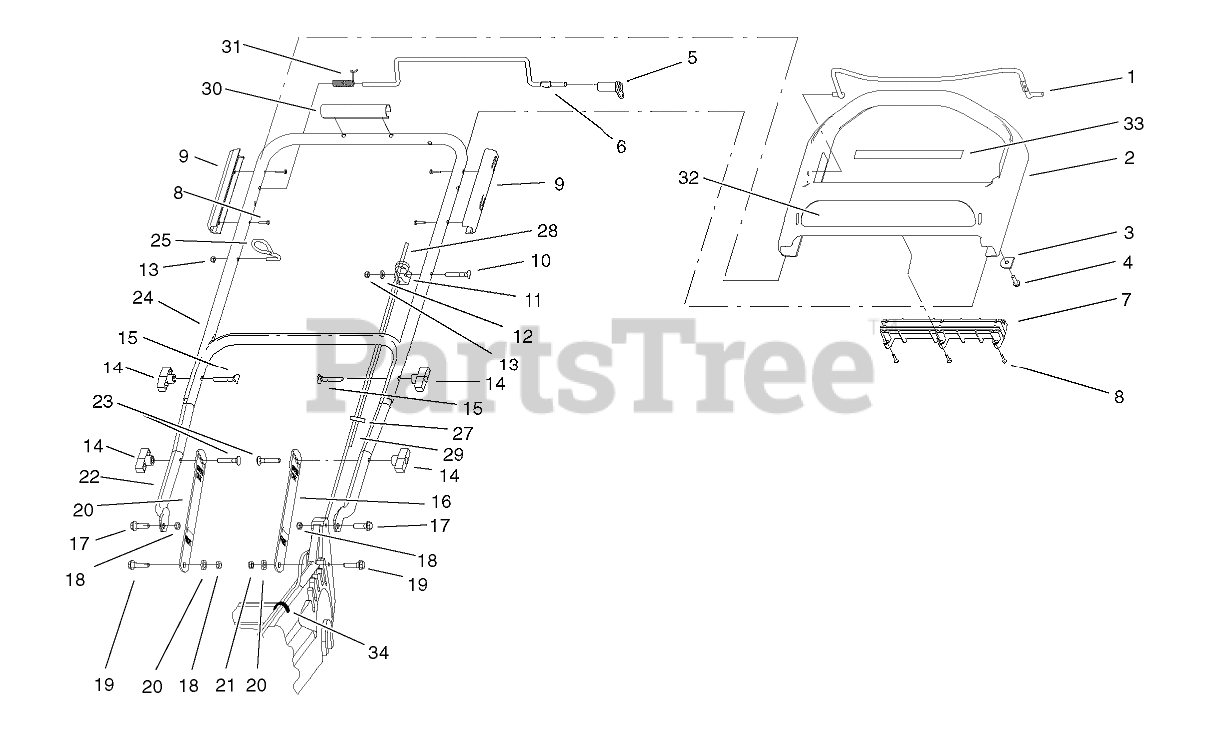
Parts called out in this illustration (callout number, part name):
1	BAIL-BRAKE
2	HANDLE-CONTROL
3	RETAINER-CABLE, BRAKE
4	SCREW-HWH
5	LEVER-TRACTION
6	BAR-CONTROL, TRACTION
7	RETAINER-CONTROL ROD, TRACTION
8	SCREW-PPH
9	GUIDE-HANDLE, CONTROL
10	SCREW
11	ANCHOR-CABLE
12	WASHER-FLAT
13	NUT-LOCK, NI
14	KNOB-HANDLE
15	SCREW-HANDLE
16	LATCH-HANDLE
17	SCREW-SHOULDER
18	NUT-LOCK, NI
19	SCREW-SHOULDER
20	SPACER
21	NUT-LOCK, NI
22	Handle-Lower(Only on: 20791)
22	Handle-Lower(Only on: 20789)
23	SCREW-CARR
24	HANDLE-UPPER
25	GUIDE-ROPE
27	TIE-CABLE
28	CABLE-BRAKE
29	CABLE-TRACTION
30	COVER-HANDLE
31	SPRING-TORSION, RH
32	DECAL-AUTOMATIC
33	DECAL-PANEL, REAR
34	Tie-Cable(Only on: 20789)
